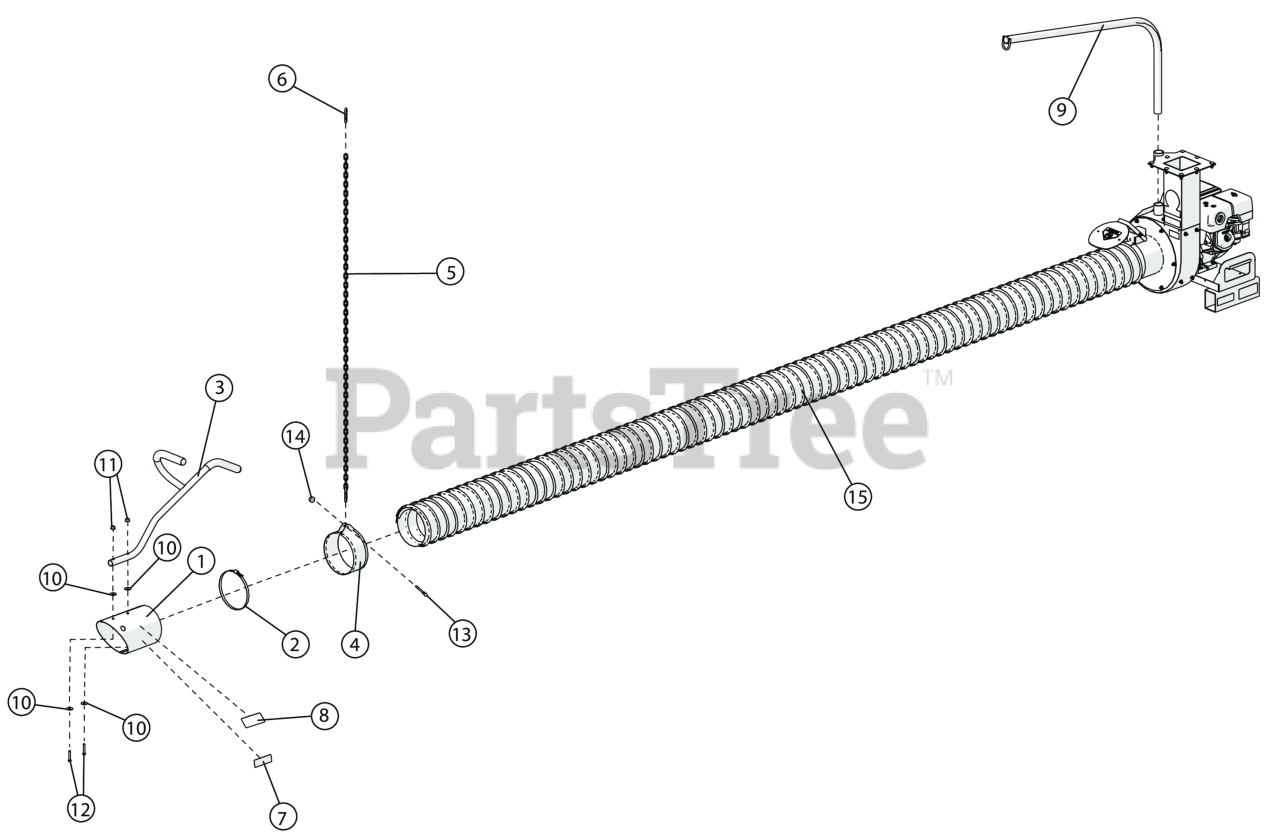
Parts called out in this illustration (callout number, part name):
1	SEE: 811007-S
2	CLAMP HOSE 8" RAW
3	SEE: 791116-S
4	BAND HOSE BOOM 8" FORMED
5	CHAIN 73 LINKS DL
6	HOOK, SNAP SAFETY 5/16" ZP
7	LABEL WARNING HOSE TRAY QL23
8	LABEL WARNING ENGINE OVERHEAT
9	BOOM WA DL
10	WASHER FLAT FENDER 5/16
11	NUT-HEX-NYLK, FLG .3125-18 ZP
12	SCREWCAP 5/16"-18X2" HCS ZP
13	SCREWCAP 1/4"-20X2 3/4" HCS ZP
14	NUT-HEX-NYLK, FLG .250"-20 ZP
15	HOSE 8" INTAKE X 10' (SEE ACCESSORY PRICELIST)
